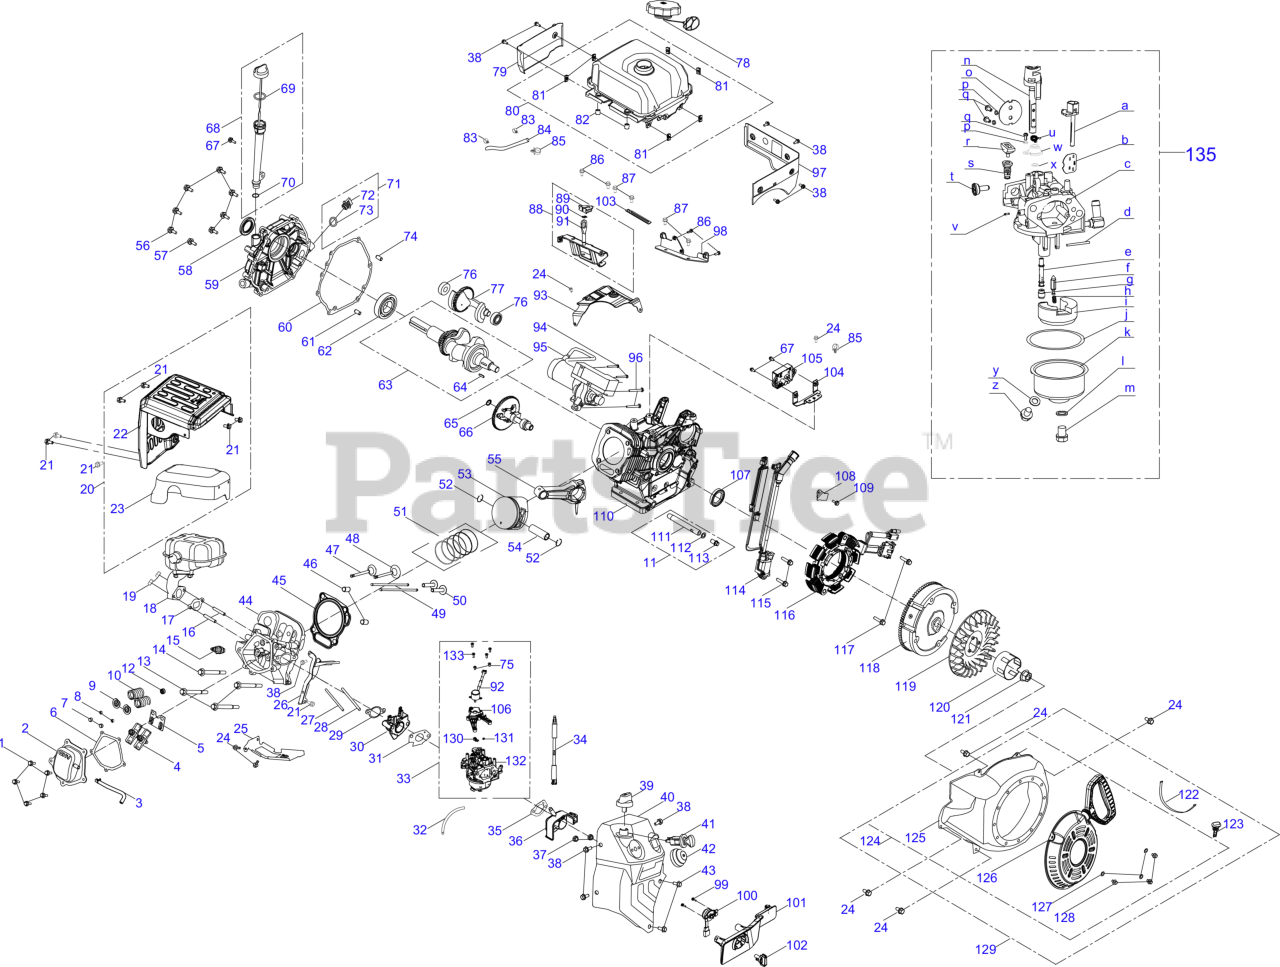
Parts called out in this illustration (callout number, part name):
1	BOLT M6 x 16
2	VALVE COVER
3	BREATHER HOSE
4	ROCKER ARM ASSEMBLY
5	PUSH ROD GUIDE
6	VALVE COVER GASKET
7	EXHAUST VALVE ADJUSTER
9	VALVE SPRING SEAT
10	VALVE SPRING
11	OIL DRAIN PIPE
12	INTAKE VALVE SEAL
13	SCREW M10-1.25 x 87 x GR10.9
14	SCREW M10-1.25 x 65 x GR10.9
15	SPARK PLUG (F6RTC/RN11YC/BPR6ES)
16	STUDS M8-1.25 x 48.5
17	MUFFLER GASKET
20	MUFFLER SHIELD ASSEMBLY
21	BOLT M6-1 x 10 GR8.8
22	MUFFLER SHIELD (OUTER)
23	MUFFLER SHIELD (INNER)
24	BOLT M6-1 x 12 GR8.8
25	CYLINDER BAFFLE
26	RECOIL SNOW GUARD
27	CARBURETOR STUD
28	STUD M6 x 123
29	CARBURETOR INSULATOR GASKET
31	CARBURETOR INSULATOR GASKET
32	PRIMER HOSE
33	CARBURETOR ASSEMBLY
34	CHOKE KNOB SHAFT
35	HEATER BOX CARBURETOR GASKET
36	HEATER BOX
38	BOLT M6-1 x 14 GR8.8
40	CONTROL PANEL
41	ENGINE KEY SWITCH ASSEMBLY
43	SCREW M6-1 x 20 CL5.8
44	CYLINDER HEAD (690-WU) ZS
45	CYLINDER HEAD GASKET
47	EXHAUST VALVE
48	INTAKE VALVE
49	PUSH ROD
50	TAPPET
51	PISTON RING KIT
52	PISTON PIN SNAP RING
54	PISTON PIN
55	CONNECTING ROD ASSEMBLY
56	SCREW M8-1.25 x 38 GR10.9
57	BOLT M8 x 45
59	CRANKCASE COVER
60	CRANKCASE COVER GASKET
62	BALL BEARING
63	CRANKSHAFT ASSEMBLY
64	WOODRUFF KEY
67	BOLT M6-1 x 18 GR8.8
68	DIPSTICK OIL ASSEMBLY
71	OIL DRAIN PLUG
72	OIL PLUG
74	DOWEL PIN
75	SCREW M4x8
76	BALL BEARING
77	BALANCE GEAR ASSEMBLY
79	FUEL TANK BACK PANEL
80	FUEL TANK ASSEMBLY
81	THREADED TAB
83	CARBURETOR HOSE CLAMP
85	FUEL LINE SUPPORT CLAMP
87	BOLT M8-1.25 x 14 GR8.8
88	FUEL TANK MOUNTING BRACKET
89	RUBBER GROMMET
90	RUBBER GROMMET
91	FUEL TANK MOUNTING BRACKET
92	STEPPER MOTOR
93	GOVERNOR GEAR BRACKET
95	ELECTRIC STARTER
96	BOLT M8-1.25 x 55 GR8.8
97	FUEL TANK FRONT PANEL
98	FUEL TANK BASE BRACKET
100	SPEED CONTORL SWITCH
101	SPEED KNOB COVER
102	SPEED CONTROL KNOB
104	ECM BRACKET
106	MOTOR BASE
108	ALTERNATOR WIRE CLAMP BRACKET
109	BOLT M6-1 x 8 GR8.8
110	CRANKCASE COMPLETE
111	OIL DRAIN PIPE
112	FLAT WASHER
113	OIL DRAIN PLUG
114	IGNITION MODULE
115	IGNITION COIL BOLT M6-1 x 28 GR8.8
116	CHARGING COIL
117	BOLT-M6-1 x 30 GR8.8
119	COOLING FAN
120	STARTER CUP
121	FLYWHEEL NUT M16X1.5
122	CABLE TIE - 3 x 150
123	IGNITION KEY
124	BLOWER HOUSING ASSEMBLY
125	BLOWER HOUSING
126	RECOIL START ASSEMBLY
127	FLAT WASHER
128	BOLT M6 x 10
129	RECOIL STARTER
130	GUIDE CLAMP
131	DAMPER SPRING
132	CARBURETOR
133	SCREW M4-0.7x10
